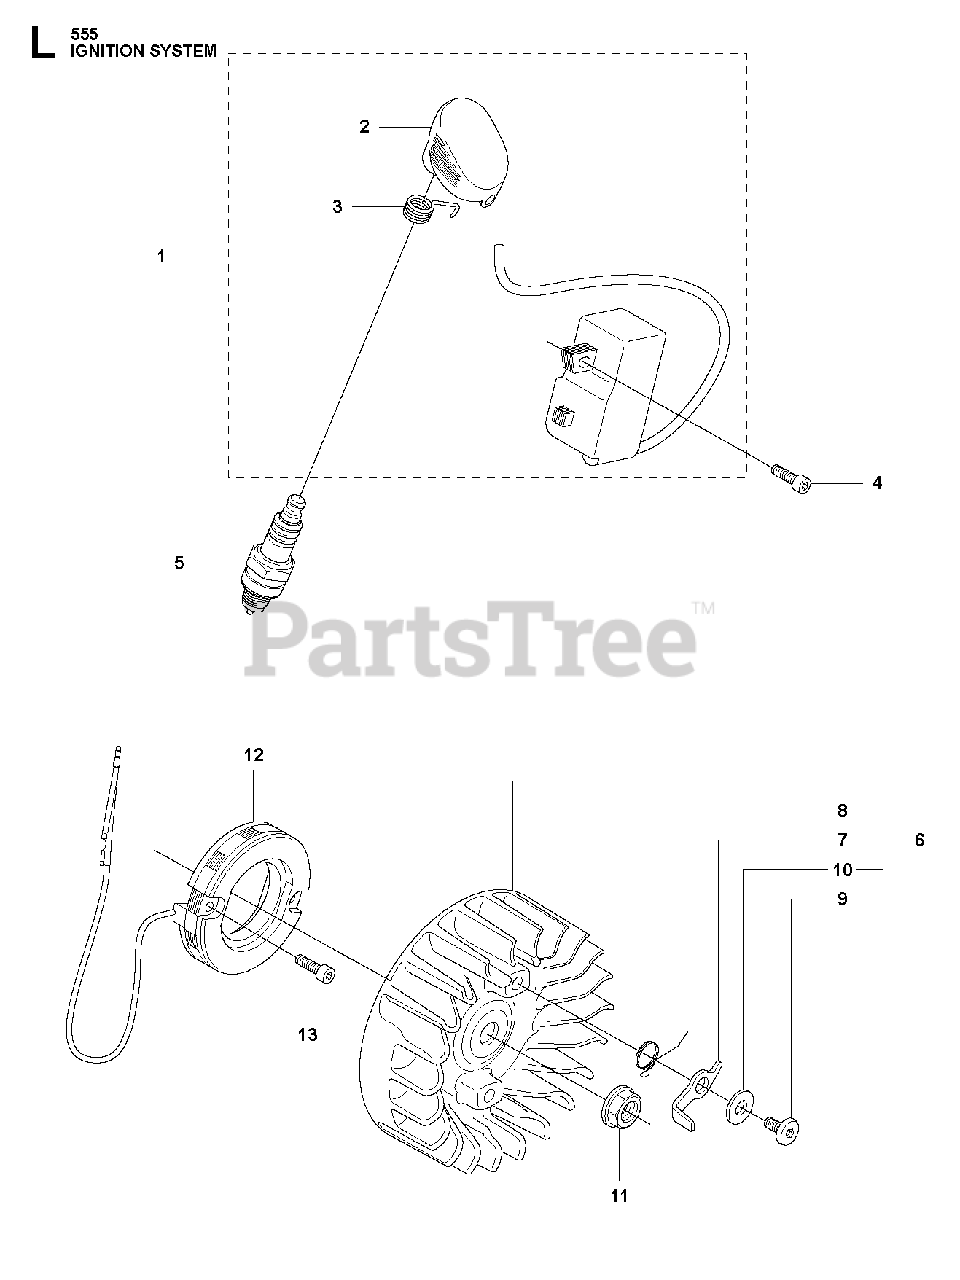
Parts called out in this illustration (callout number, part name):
1	RP IGNITION MODULE
2	SPARK PLUG CAP
3	SPRING
5	BPMR7A NGK SPARK PLUG
6	FLYWHEEL ASSY
7	STARTER PAWL
8	SPRING
9	SCREW
10	WASHER
11	NUT W/ WASHER
12	GENERATOR STARTER
13	SCREW
